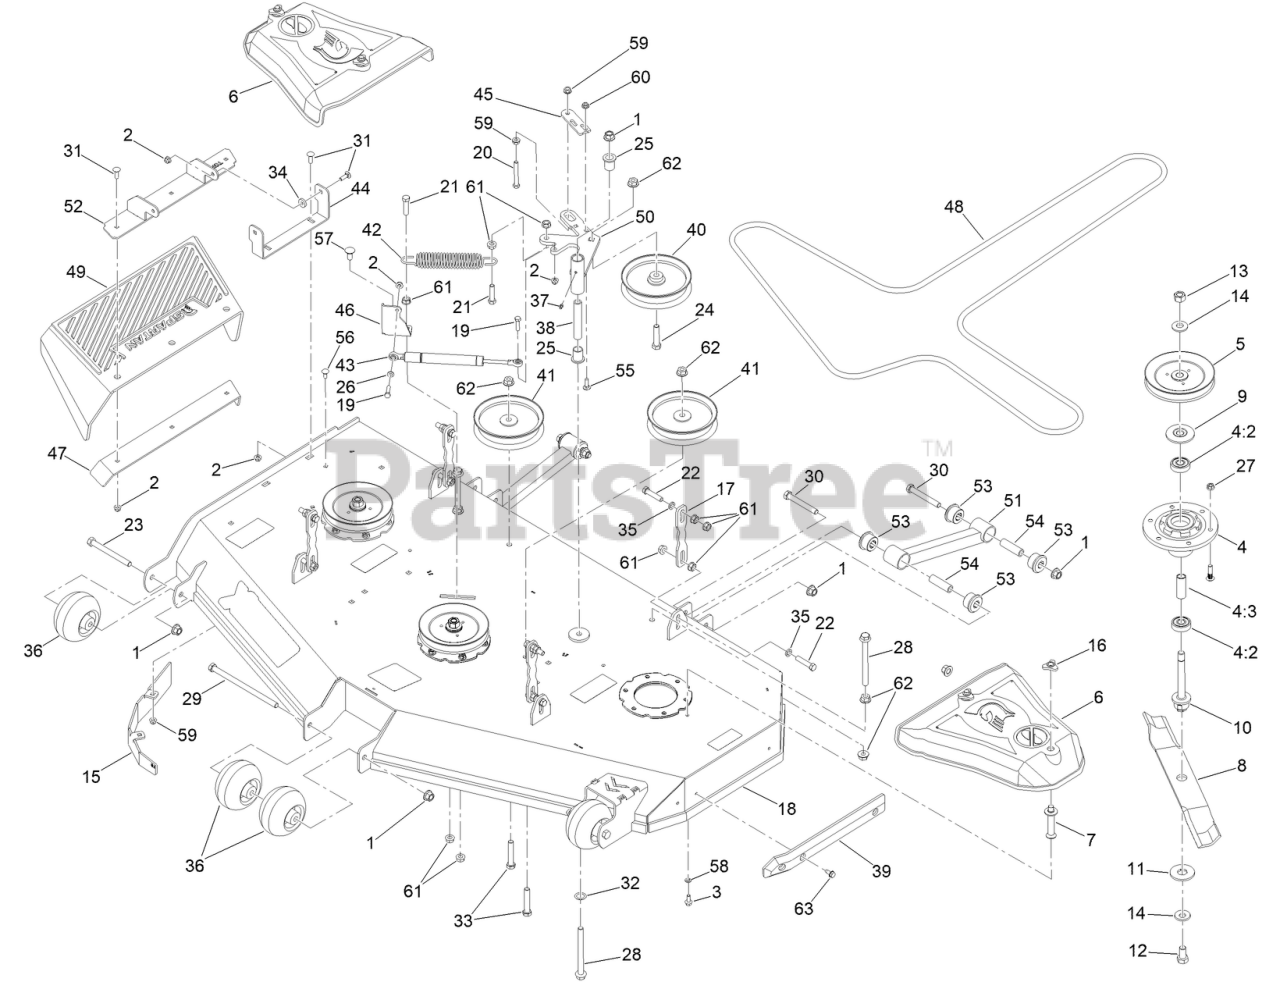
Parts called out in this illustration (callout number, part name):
1	NUT-LOCK
2	NUT-HF, NI
3	SCREW-HHF
4	SPINDLE ASM 5IN DECK
4:2	BEARING
4:3	SPACER, BEARING
5	PULLEY
6	COVER-BELT
7	PIN-BELT COVER
8	BLADE-ROTARY
9	GUARD-BEARING TOP 0.673IN
10	SHAFT - SPINDLE
11	WASHER-HEX
12	M16X1.5-30MM C10.9 HEX BOLT
13	M16X1.5 C8.8 HEX NUT
14	M16 SPRING WASHER (39MMOD/ 3.9MM THK)
15	BAFFLE-WIPER 61 PAINTED BLACK
16	NUT-KNOB
17	HANGER-DECK PAINTED BLACK
18	ASM-DECK W/ DECALS
19	SCREW-HH
20	SCREW-HH
21	SCREW-HH
22	SCREW-HH
23	SCREW-HH
24	SCREW-HH
25	3/4IN ID X15/16IN OD X 1-1/8IN FLNG BUSH
26	.312IDX.625ODX.062 THK THRUST BRG OI BRZ
28	1/2-13 X 5-1/2 HEX FLANGE BOLT GR 8 ZY
29	1/2-13 X 8-1/2 HEX C/S GR 2 ZINC YELLOW
30	1/2-13 X 3-3/4 HEX C/S (GR.5) ZC/YEL
31	5/16-18 X 1 CARRIAGE BOLT GR 8 YZ
32	.767IDX1.125ODX.016 THK TRIP WV WASHER
33	1/2-13 X 2-3/4 HEX FLANGE BOLT (GR.8) YZ
34	.312 ID X .875OD X .1875 THK F/W NYL
35	.443 ID X .749 OD X .125 THK NYLON BLACK
36	MWR ANTI-SCALP WHL W/O GREASE FITTING
37	1/4IN DRIVE TYPE GREASE FITTING YZ
38	MWR INNER IDLER SPACER
39	MWR NYLON DECK GUARD
40	6-3/4IN IDLER PULLEY 7/16IN SPACER ASM
41	6-3/4IN IDLER PULLEY 15/16IN SPACER ASSY
42	MWR DECK SPRING
43	IDLER GAS SPRING
44	MWR CHUTE MTG BRKT BLACK
45	DECK IDLER PULLEY BELT RETAINER BRKT
46	DECK BELT IDLER DAMPER MTG BRKT BLACK
47	MWR DECK CHUTE HINGE BACKER BRKT
48	61 DECK BELT
49	RZ MWR RUBBER DISCHARGE CHUTE
50	MWR DECK IDLER PULLEY ARM ASSY BLACK
51	RZ MWR DECK STABLZR ASSY
52	MWR DECK CHUTE HINGE ASSY
53	RED A80 SUSP BUSHING
54	UTV A-ARM BUSHING SLEEVE
55	BOLT-CARR
56	3/8-16 X 1 CARRIAGE BOLT YZ GR.8
57	SCREW-CARR
58	WASHER-LOCK
59	3/8-16 HEX FLANGE NUT W/SERR ZINC YELLOW
61	NUT-HF
62	NUT-HHF
63	SCREW-HWH, THREAD CUT
